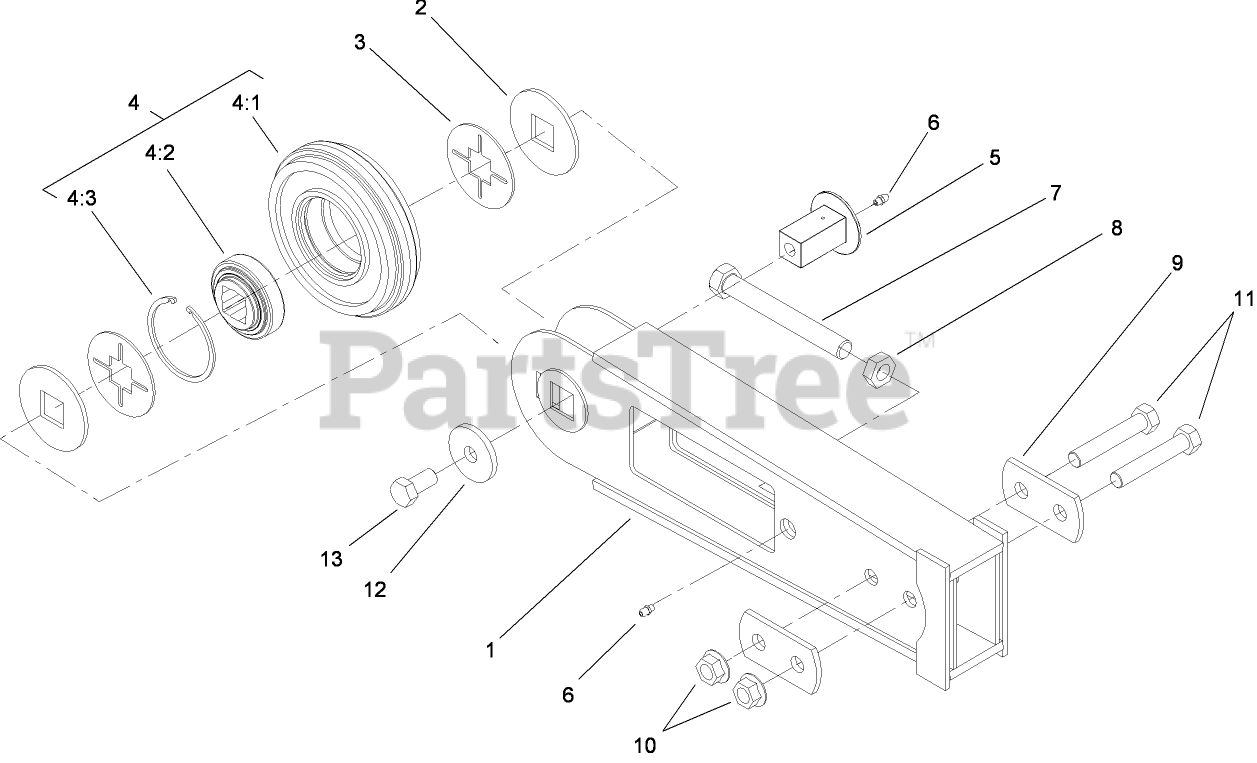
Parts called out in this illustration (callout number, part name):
1	BOOM ASM
2	CAP-ROLLER
3	SPACER-ROLLER
4	TRENCHER ROLLER ASM
4:1	ROLLER-NOSE
4:2	BEARING
4:3	RING-RETAINING
5	AXLE-ROLLER
6	FITTING-GREASE
7	BOLT-ADJUSTMENT
8	NUT-JAM
9	PLATE-SUPPORT
10	NUT-FLANGE
11	SCREW-HH
12	WASHER
13	SCREW-HH
